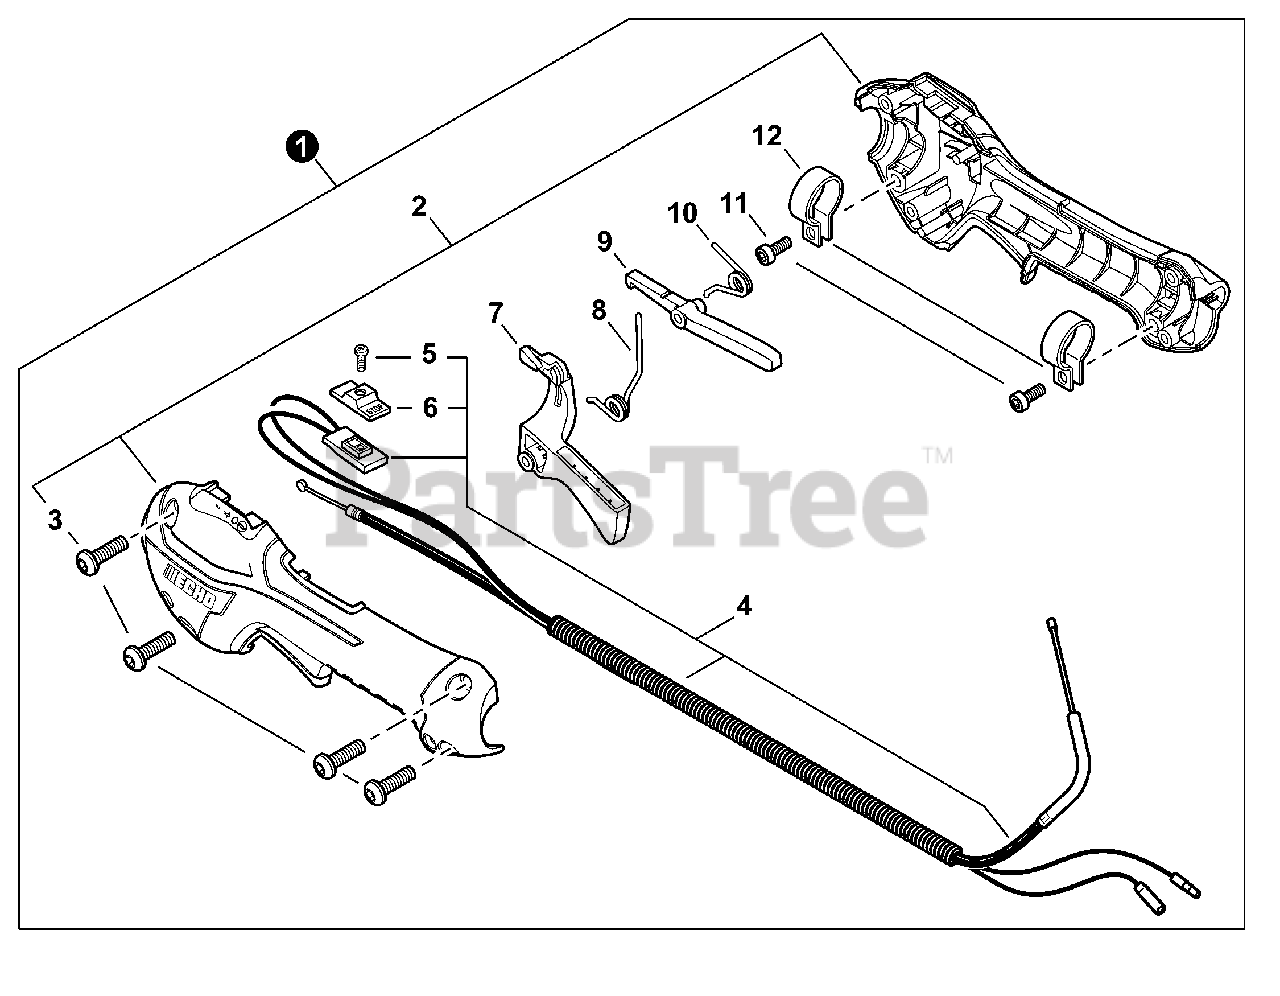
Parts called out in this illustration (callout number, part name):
1	CONTROL HANDLE ASSY
2	CONTROL HANDLE KIT
3	BOLT, TORX 5×16
4	CABLE ASSY, CONTROL
5	SCREW 3×10
6	KNOB, SWITCH - ORANGE
7	TRIGGER, THROTTLE
8	SPRING, TORSION
9	LEVER, THROTTLE LOCKOUT
10	SPRING, TORSION
11	BOLT, TORX 5×16
